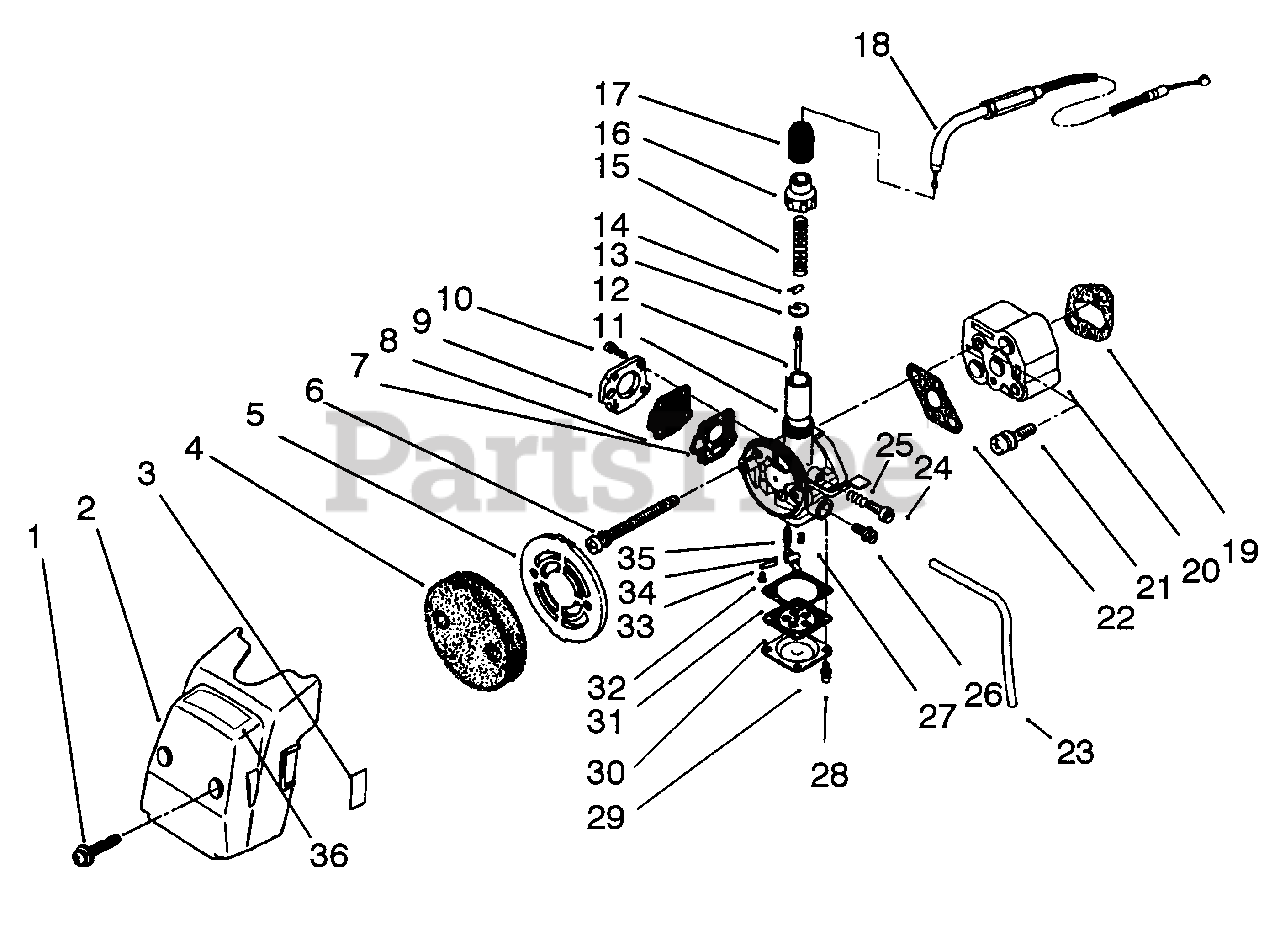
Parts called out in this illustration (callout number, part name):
1	Screw/Washer
2	Case-Cleaner
3	Label-Choke
4	Element
6	Screw/Washer
7	Gasket-Pump
8	Diaphragm-Pump
9	Pump Cover Assembly
10	Screw/Washer
11	Valve-Throttle
12	Needle Jet Assembly
13	Retainer-Spring
14	Clip-Needle
15	Spring-Throttle
16	Cap-Mixing Chamber
17	Cap-Rubber
18	Cable-Throttle
19	Gasket-Insulator
20	Insulator
21	Screw/Washer
22	Gasket-Carburetor
23	Tube-Fuel
24	Screw-Adjusting
25	Spring-Adjusting
26	Jet Main
27	Spring-lnlet Valve
28	Screw/Washer
29	Cover-Diaphragm
30	Diaphragm
31	Gasket-Diaphragm
32	Setscrew
33	Pin-Float
34	Arm-Float
35	Valve-Float
36	Decal-Fuel Mix
